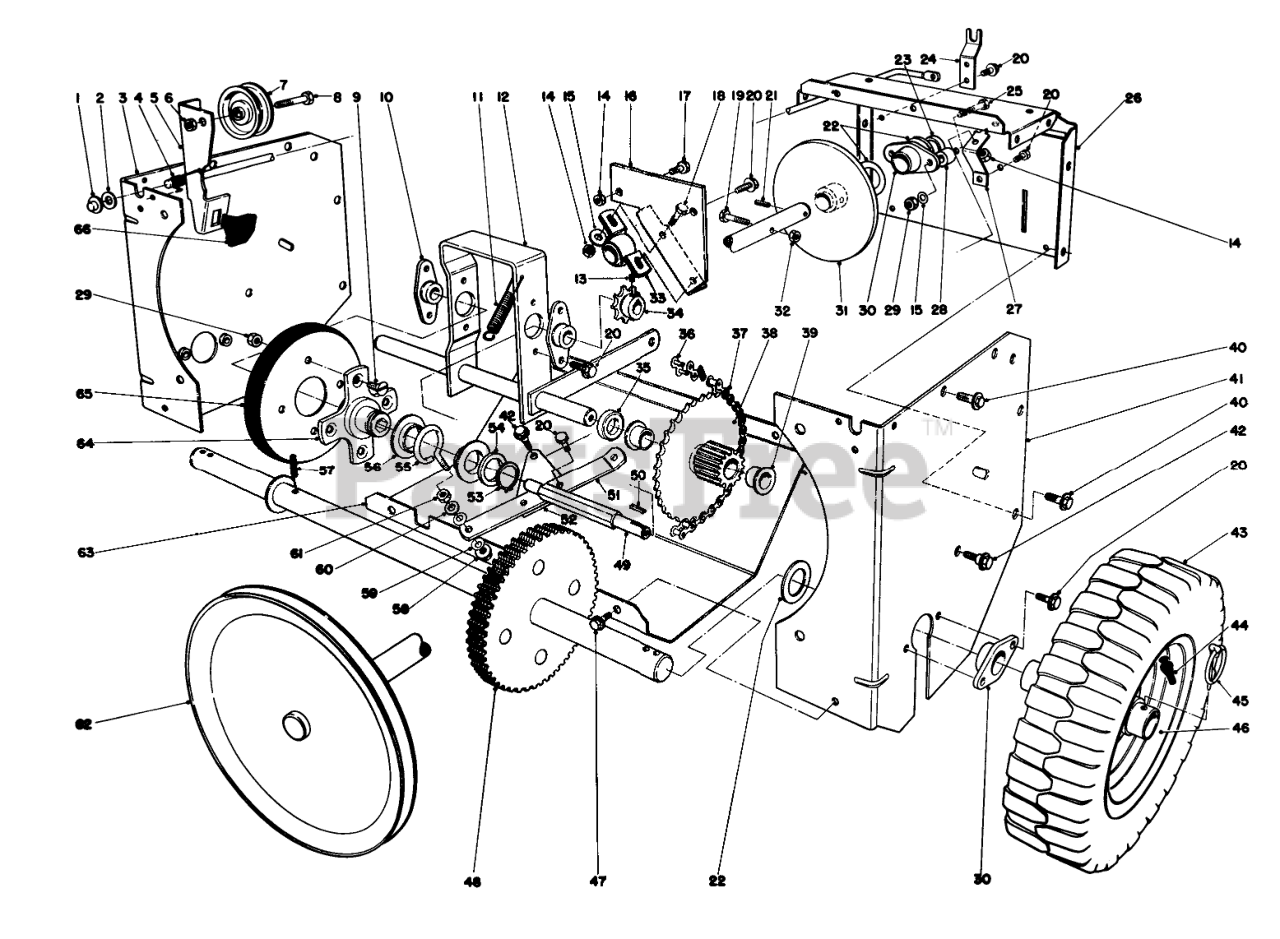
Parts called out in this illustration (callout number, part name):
1	PUSH NUT
2	WASHER-FLAT
3	RH TRACT SIDE PLT R
4	TORSION CLUTCH SPRING
5	Clutch Rod (Incl. Ref. #66)
6	NUT-HEX
7	PULLEY-IDLER
8	SCREW-HH
9	5/16-18X5/8 FLT HD MS
10	BEARING-WHEEL, FRICTION
11	TENSION SPRING
12	PIVOT SHAFT WA B
13	SCREW-HSH
14	NUT-LOCK, NI
15	WASHER-PLAIN
16	SHAFT SUPT BRKT B
17	SCREW-HH
18	SCREW-HH
19	SCREW-HH
20	SCREW-HWHTF
21	Roll Pin
22	WASHER
23	DRIVE SHAFT SPACER
24	CLUTCH ROD SUPPORT
25	SCREW-HH
26	CENTER FRAME R
27	PIVOT BRACKET
28	BRG STANDOFF
29	Nut
30	AXLE BEARING
31	FRICTION PLT WA
32	NUT-LOCK, CONE
33	PILLOW BLOCK BRG
34	SPROCKET
35	COSHAFT SPACER
36	LINK-CONNECTING
37	ROLLER-CHAIN
38	Gear & Bushing (Incl. Ref. #39)
39	BUSHING
40	SCREW-HHFTF
41	LH TRACT SIDE PLT R
42	SHOULDER SCREW
43	Tire
44	STEM-VALVE
45	PIN-LYNCH
46	Wheel
47	SCREW-HWH
48	AXLE & GEAR WA
49	FRICTION WHL SHAFT
51	SHIFT LINKAGE
52	PIVOT PLATE
53	RING-RETAINING
54	WASHER-THRUST
55	SLIDER RING COLLAR
56	SLIDER RING
57	PIN-ROLL, SLOTTED
58	NUT-LOCK, FLANGE
59	WASHER-SPRING
60	WASHER-FLAT
61	Nut
62	PULLEY/SHFT WA
63	LOWER SHIELD R
64	TRACTION DISC HUB
65	FRICTION WHEEL
66	Brake Pad
